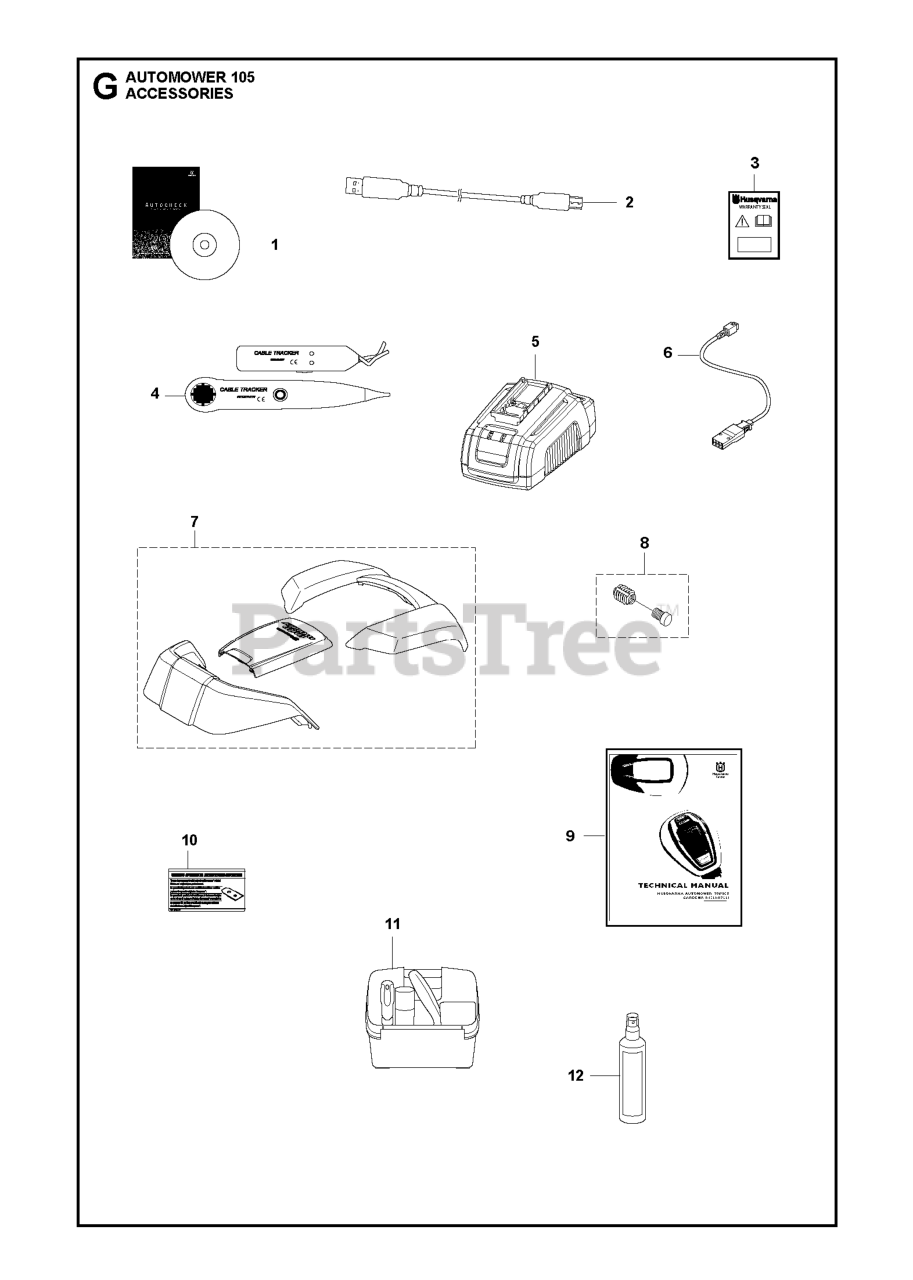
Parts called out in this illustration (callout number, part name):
1	DVD AUTOCHECK EXP SERVICE
2	CABLE WHITE ALT GREY
3	LABEL WARRANTY SEAL DEALER
4	TEST EQUIPMENT
5	CHARGER BATTERY TEST
6	CABLE ASSY QUICK CHARGER
8	THREAD INSERT KIT: THREAD INSE
10	ORIGINAL PARTS STICKER
10	DECAL WARNING ORIGINAL BLADE E
11	CLEANING AND MAITENANCE KIT AM
12	AUTOMOWER ACCY
